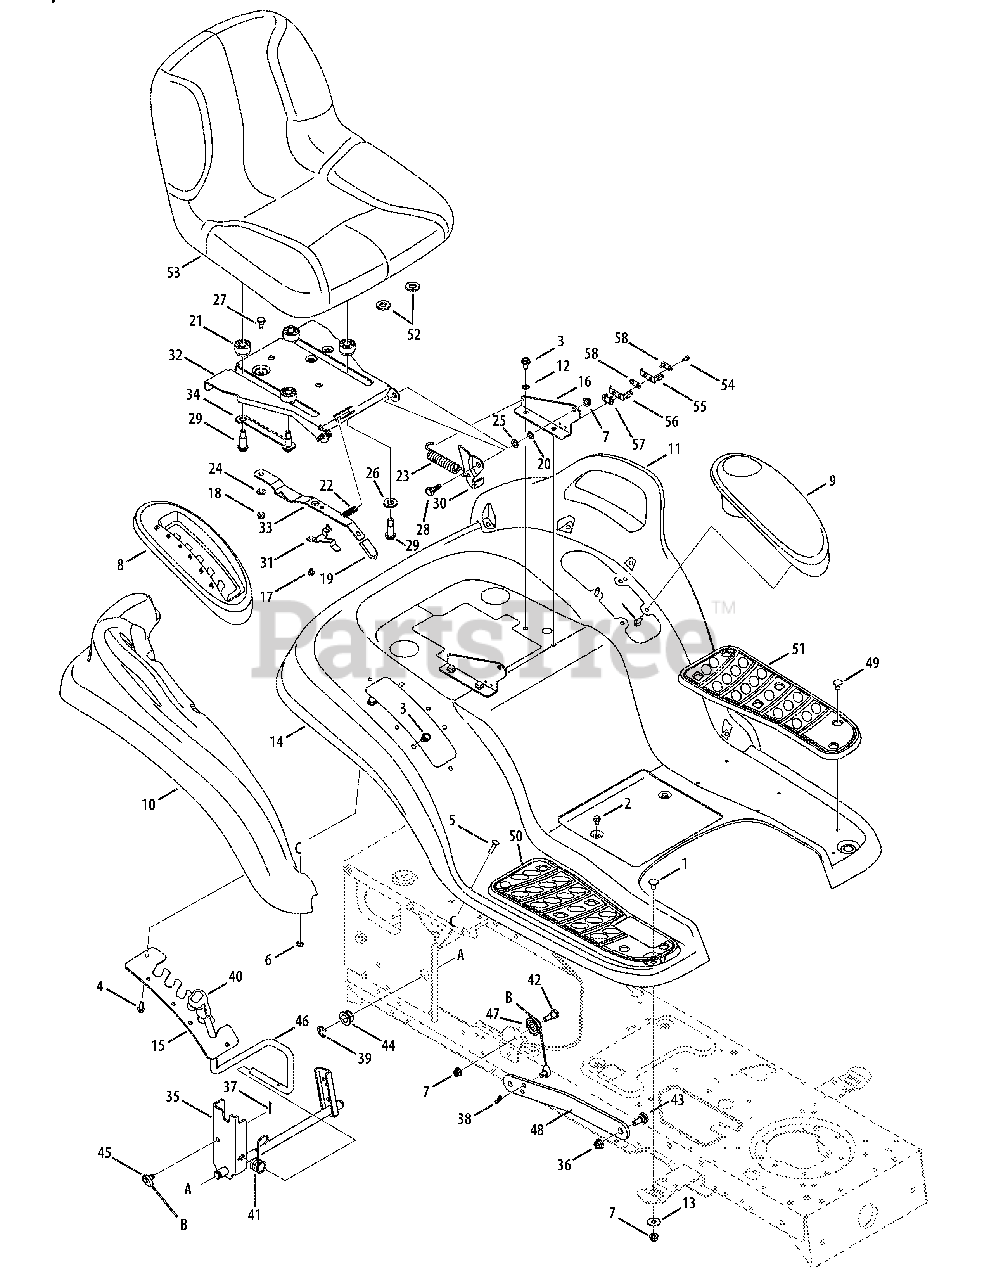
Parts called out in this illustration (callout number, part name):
1	Carriage Bolt, 5/16-18 x.750
2	Screw, 1/4-20 x.500
3	Screw, 5/16-18 x .750
4	Self-tapping Screw, 1/4-15 x.75
5	Carriage Screw 1/4-20 x 1.00
6	Sems Nut 1/4-20
7	Flange Lock Nut, 5/16-18
8	Lift Lever Cover
9	Cover w/ Cup Holder
10	RH Fender Flare
11	LH Fender Flare
12	Lock Washer, 5/16
13	Flat Washer,.349 x 1.0 x.063
17	Screw, #10-16 x.375
18	Flange Lock Nut, 1/4-20
19	Seat Adjuster Grip
20	Speed Clip
21	Spacer
22	Compression Spring,.41 x 1.5
23	Extension Spring,.84 x 4.6
24	Washer, Flat, .344 x .62 x .033
25	Flat Washer
26	Flat Washer,.31 x 1.062 x.134
27	Shoulder Screw,.340 x.285,1/4-20
28	Shoulder Screw,.437 x.286
29	Shoulder Screw,.50 x.50, 3/8-16
30	Seat Lift Bracket
31	Seat Stop
34	Seat Adjustment Selector
37	Hairpin Clip
38	Cotter Pin
39	E-Ring
40	Handle Grip
41	Torsion Spring
42	Hex Cap Screw, 5/16-18 x.62
43	Shoulder Screw, 3/8-16
44	Hex Flange Bearing
45	Lift Cable, 16.16
46	Lift Handle
47	Roller Pulley
49	Foot Pad Clips
50	RH Foot Pad
51	LH Foot Pad
52	Flat Washer, .406 x .875 x .059
53	High Back Seat, Black
54	Screw, #8-18 x.500
55	Outer Seat Spring Switch
56	Inner Seat Spring Switch
57	Insulator Boss Plate
58	Insulator Plate
